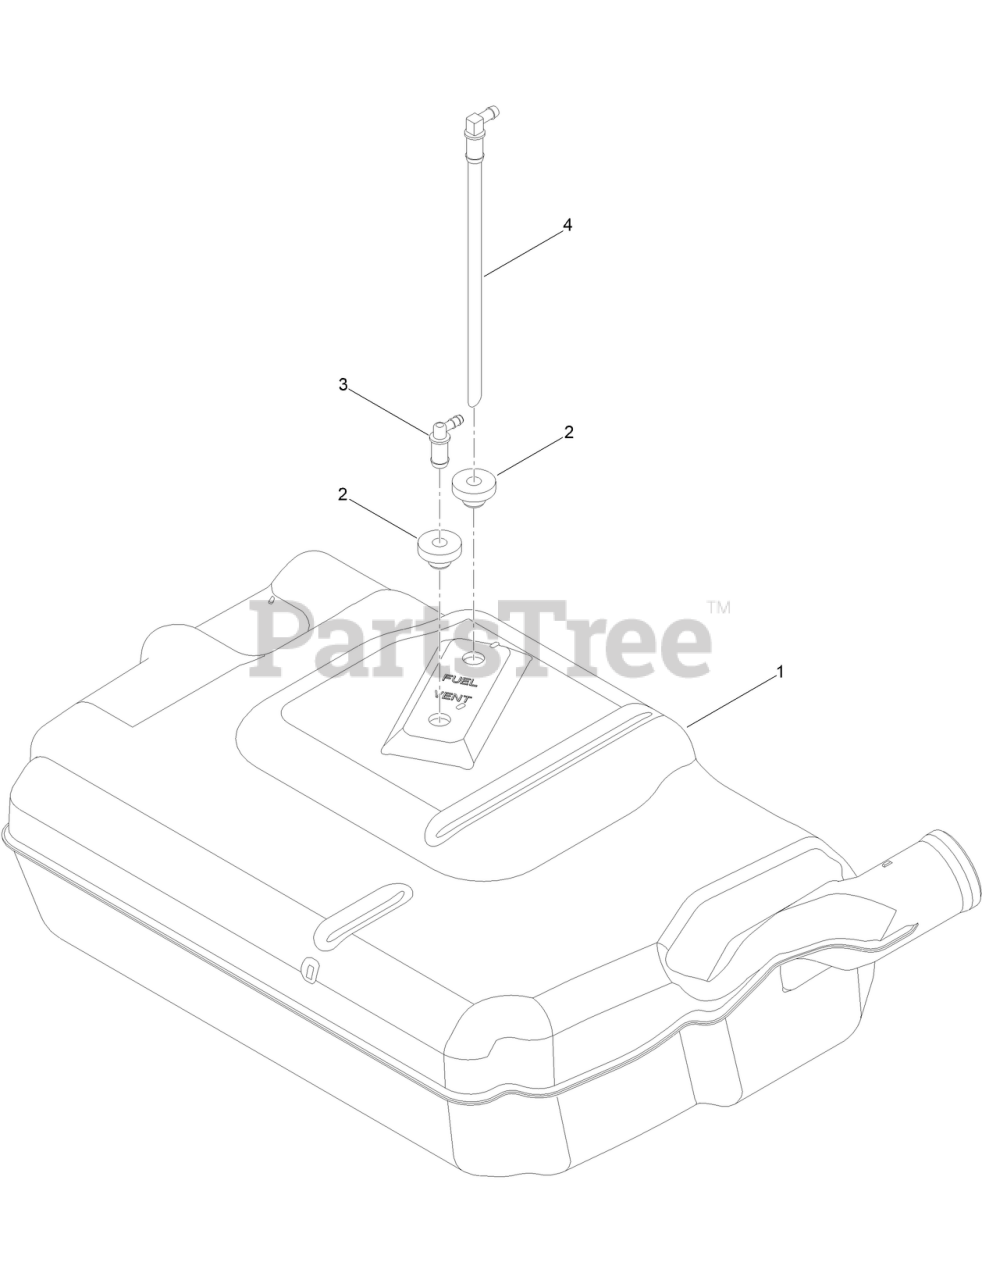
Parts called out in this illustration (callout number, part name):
1	TANK-FUEL
2	BUSHING
3	FITTING-ELBOW 90
4	FITTING-PICKUP, FUEL
